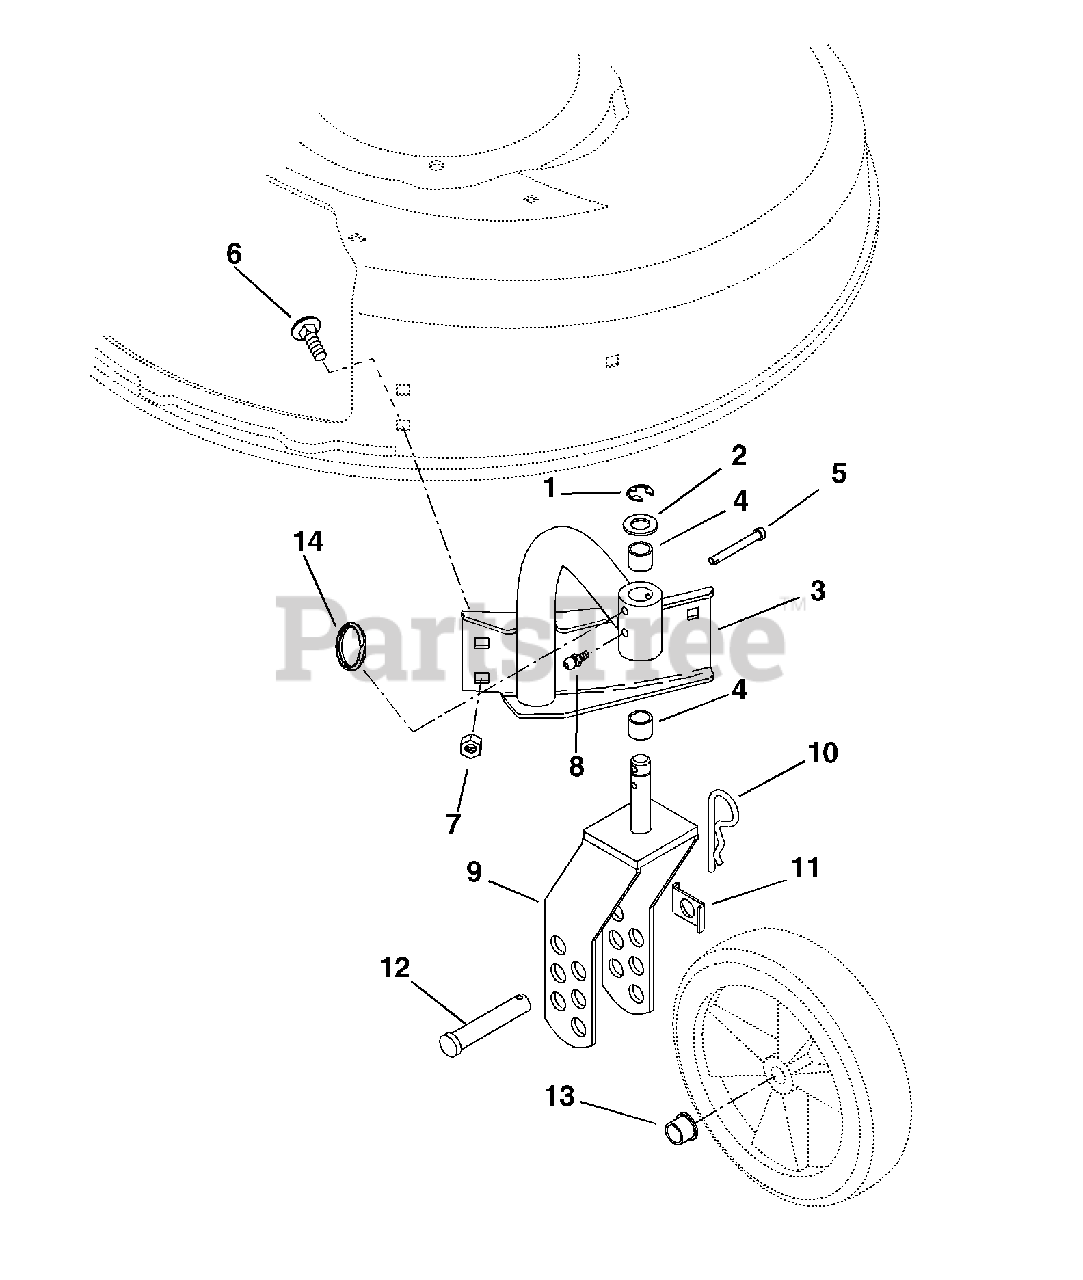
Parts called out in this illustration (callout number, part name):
1	RG-RTNG-EXT .625X.042
2	WSHR-FL-STL .630X1.005X.062 YZ
3	RIGHT MOUNT ARM WELDMENT
4	BSHG-SLV .625X.750X.500 BR
5	PIN-CLEV .25X1.75 YWZC
6	@BLT-RDHDSQNK .31-18X.50 G5YZ
7	@NUT-SPNLK-FLG .312-18 YWZC
8	FTG-LUBE .25-28X.256 YWZC
9	WHEEL YOKE WELDMENT
10	PIN-HAIR-EXT .12X.31X2.37 YWZC
11	AXLE TAB
12	PIN-CLEV .494X2.62 YWZC
13	BSHG-FLG .500X.625X.500X.750
14	KICKOUT RING YWZC
